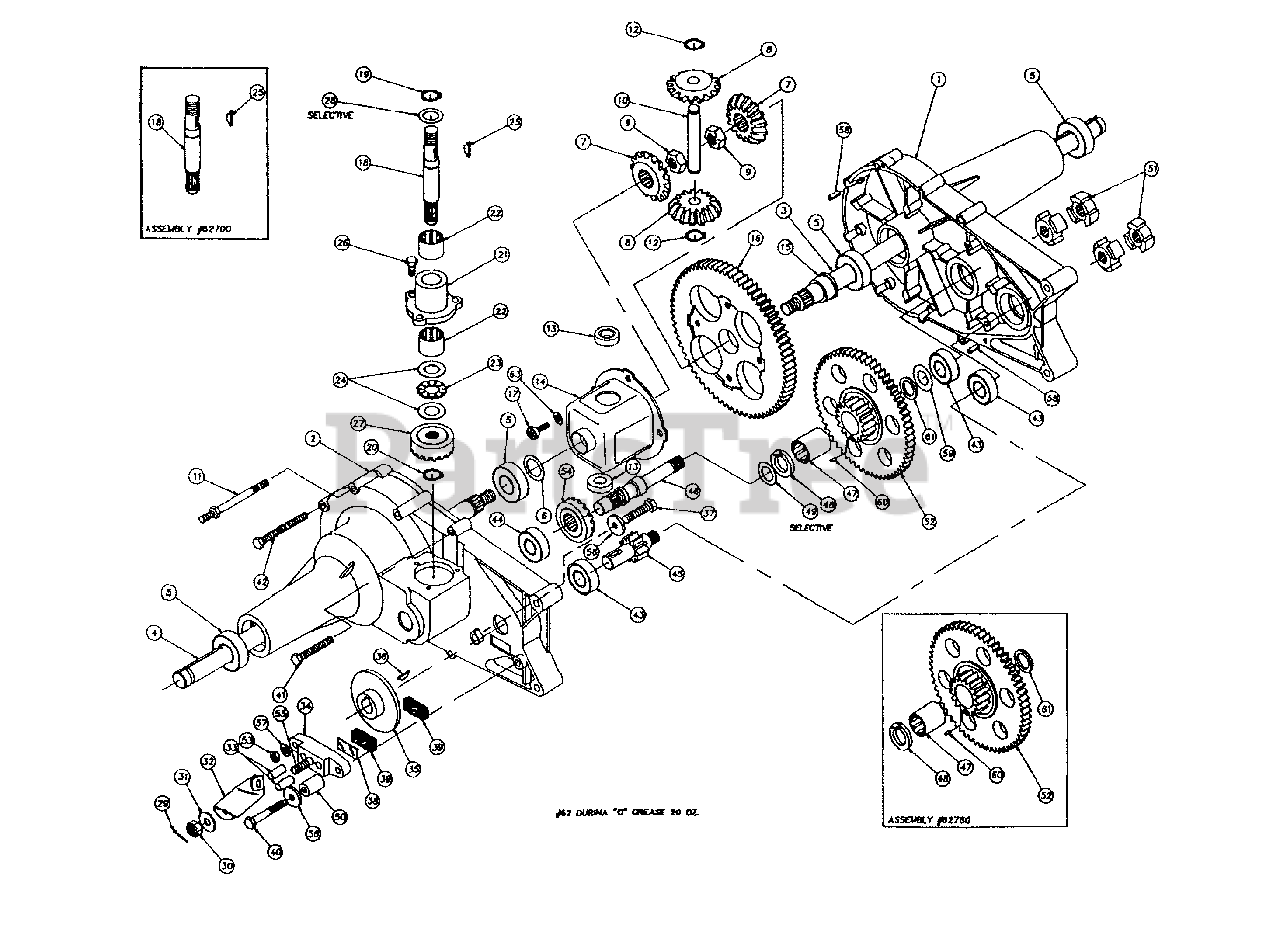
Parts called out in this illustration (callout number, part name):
1	Housing, Half L.H.
2	Housing, Half R.H.
5	Bearing, Ball
6	Washer, Flat 3/4 x 1-1/8 x .030
7	Gear, Miter
8	Gear, Miter
9	Nut, Hex Jam W/Patch 1/2-20
10	Shaft, Cross
11	Screw, Stud
12	Snap, Ring
13	Bearing, Thrust
14	Housing Assembly, Differential
15	Bearing, Flange
16	Gear, Differential 72 Tooth
17	Bolt, Torx Head 1/ 4-28 x 5/8"
18	Shaft, Input
19	Snap, Ring
20	Retaining Ring 7/16"
21	Housing, Input Bearing
22	Bearing, Needle
23	Bearing, Thrust
24	Washer, Flat 5/8 x 1-1/8 x .030
25	Key, Hi-Pro 3/32 x 5/8
26	Screw, Hex W/Patch 1/4-20 x 3/4
27	Gear, Input Pinion 17 Tooth
28	Washer, Flat .62 x 1 x .05
28	Washer, Flat .62 x 1.125 x .060
28	Washer, Flat .62 x 1 x .040
29	Pin, Cotter
30	Nut, Castle 5/16-24
31	Washer, Flat .343 x .88 x .062
32	Arm, Brake Actuator
33	Pin, Brake Actuating
34	Brake, Yoke
35	Disc, Brake
36	Key, Hi-Pro 3/16 x 5/8"
37	Screw, Hex 1/4-20 x 1.50
38	Plate, Puck
39	Puck, Brake
40	Screw, Hex W/Patch 1 /4-20 x 2.00
41	Screw, Hex Self-Tap 1/4-20 x 2.00
42	Screw, Hex Self-Tap 1/4-20 x 3.00
43	Bearing, Ball
44	Bearing, Ball
45	Shaft, Pinion W/11 Tooth Gear
46	Shaft, Drive
47	Bearing, Needle
48	Bronze Thrust Brg. 5/8 x 1-1/4 x 7/64
49	Washer, Flat .62 x 1.0 x .040
49	Washer, Flat .62 x 1.0 x .050
50	Spacer
52	Gear, 60 and 17 Tooth
53	Nut, Hex 1/4-20
54	Gear, Drive Pinion 17 Tooth
55	Bolt, Square Head
56	Washer 15/16 x .265 x .125
57	Washer 1/4" Spring Lock
58	Pin, Roll 3/16" x 1/2"
59	Washer, Flat .62 x 1.0 x .030
60	Pin, Dowel 3/32 x 1/4
61	Seal, Grease
62	Shell, Durina-O Grease (20oz.)
63	Washer, Head Spring Lock 1/4"
65	Assembly, Gear, Reduction
66	Assembly, Shaft, Input
